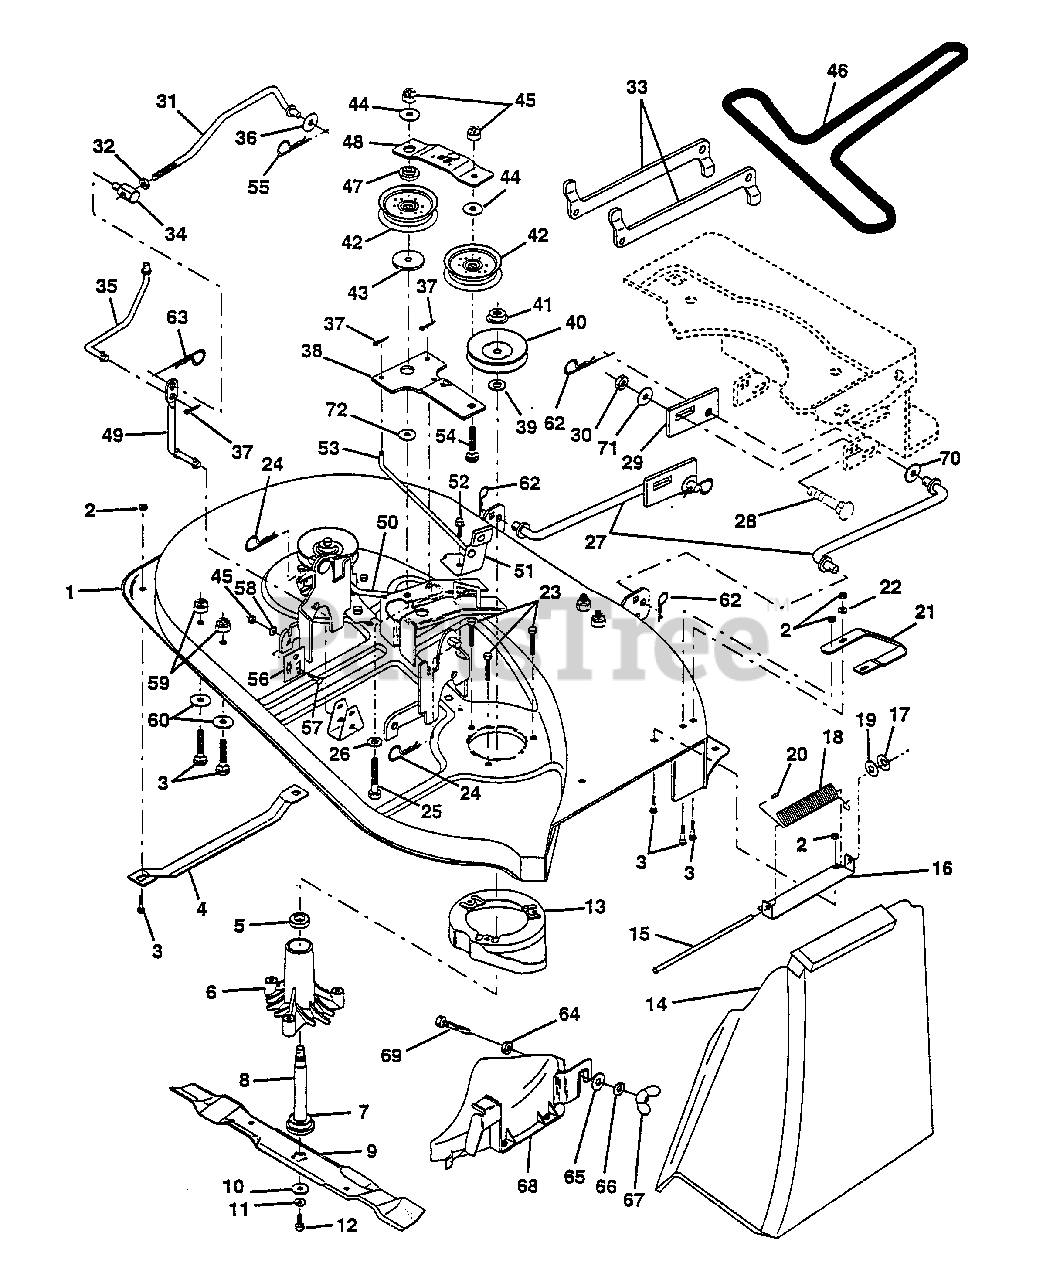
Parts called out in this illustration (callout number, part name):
1	Mower Deck Assembly
2	Nut, Lock Hx w/Ins 5/16-18
3	Bolt, Carriage 5/16-18 x 3/4
4	Runner, L.H.
6	Housing, Mandrel
8	Shaft and Bearing Assembly, Mandrel
10	Washer, Hardened
11	Washer, Lock 3/8
12	Bolt, Hex 3/8-24 x 1-1/4 Grade 8
13	Stripper, Mower, Vented
14	Shield, Deflector
15	Rod, Hinge
16	Bracket Assembly, Deflector
18	Spring, Deflector
19	Washer 11/32 x 5/8 x 16 Gauge
20	Cap, Sleeve
21	Runner, R.H.
22	Washer 11/32 x 3/4 x 16 Gauge
23	Screw Thdrol Hex Head Zinc MWR
24	Retainer, Spring
25	Bolt Hex 3/8-16 x 2-1/4
26	Washer 13/32 x 1 x 12 Gauge
27	Link Assembly, Front
28	Bolt RDHD SQNK 3/8 - 16 x 1
29	Plate Slide Link
30	Nut, Lock Hex w/washer 3/8 -16
31	Clutch Rod, Primary
32	Nut, Hex, Jam 3/8-16
33	Arm, Suspension, Rear
34	Trunnion 3/8-16
35	Clutch Rod, Secondary
36	Washer 13/32 x 13/16 x 16 Gauge
37	Pin, Cotter 3/32 x 3/4
39	Washer .150 Thick
40	Pulley, Mandrel
41	Nut, Flangelock 9/16
42	Pulley, Flat Idler
43	Spacer, Retainer
44	Washer 13/32 x 1 x 12 Gauge
45	Nut, Crownlock 3/8-16
46	Belt
47	Spacer, Idler Arm
48	Stiffener, Idler Arm
49	Rod, Pivot
50	Rod, Brake, L.H.
51	Brake Assembly
52	Screw, Hex Washer Head, Thd., Roll. 5/16-18 x 3/4
53	Rod, Brake, R.H.
54	Bolt, Carriage 3/8-16 x 1-3/4 Grade 5
55	Spring, Retainer
56	Adjustment Plate, Rear Link, L.H.
57	Bolt, Carriage 3/8-16 x 1
58	Washer 13/32 x 3/4 x 12 Gauge
59	Locknut, Hex, with Washer Insert 5/16-18
60	Washer 11/32 x 11/16 x 12 Gauge
62	Retainer Spring
63	Retainer Spring
64	Nut, Centerlock 3/8 - 16
65	Washer 13/32 x 1-1/4 x 16 Ga.
66	Washer Lock 3/8
68	Cover Asm Mulching
69	Bolt 3/8 - 16 x 1-1/4
70	Washer 1/2 x 1-1/4 x 16 Ga.
71	Washer Flat 13/32 x 1 x 10 Ga.
72	Washer Hardened
